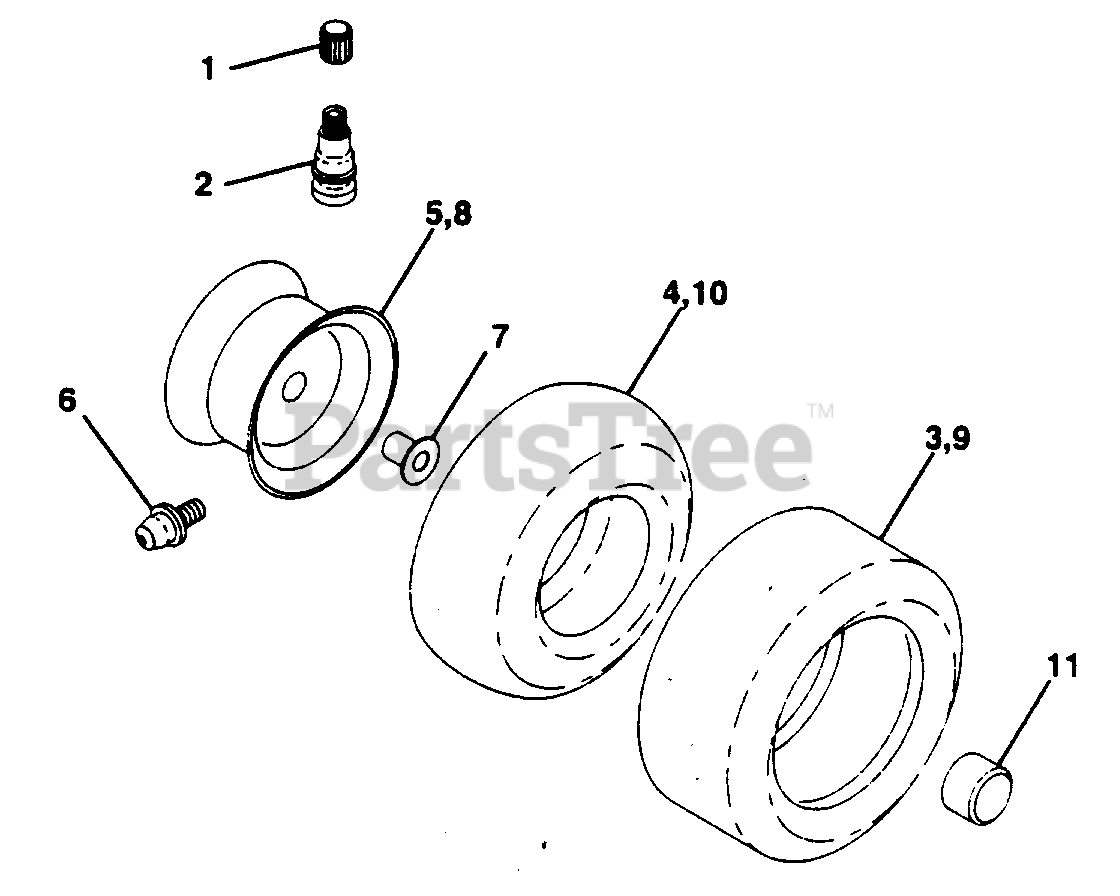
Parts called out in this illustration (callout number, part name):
1	Cap Valve Tire
3	Tire F Ts 15 X 6 0 - 6 Service
4	Tube Front (Service Item Only)
5	Rim Asm 8"rear Silver Service
6	Fitting Grease (Front Wheel Only)
7	Bearing Flange (Front Wheel Only)
8	Rim Asm 6" front Silver Service
9	Tire R Ts 20 10 C Service
10	Tube Rear (Service Item Only)
